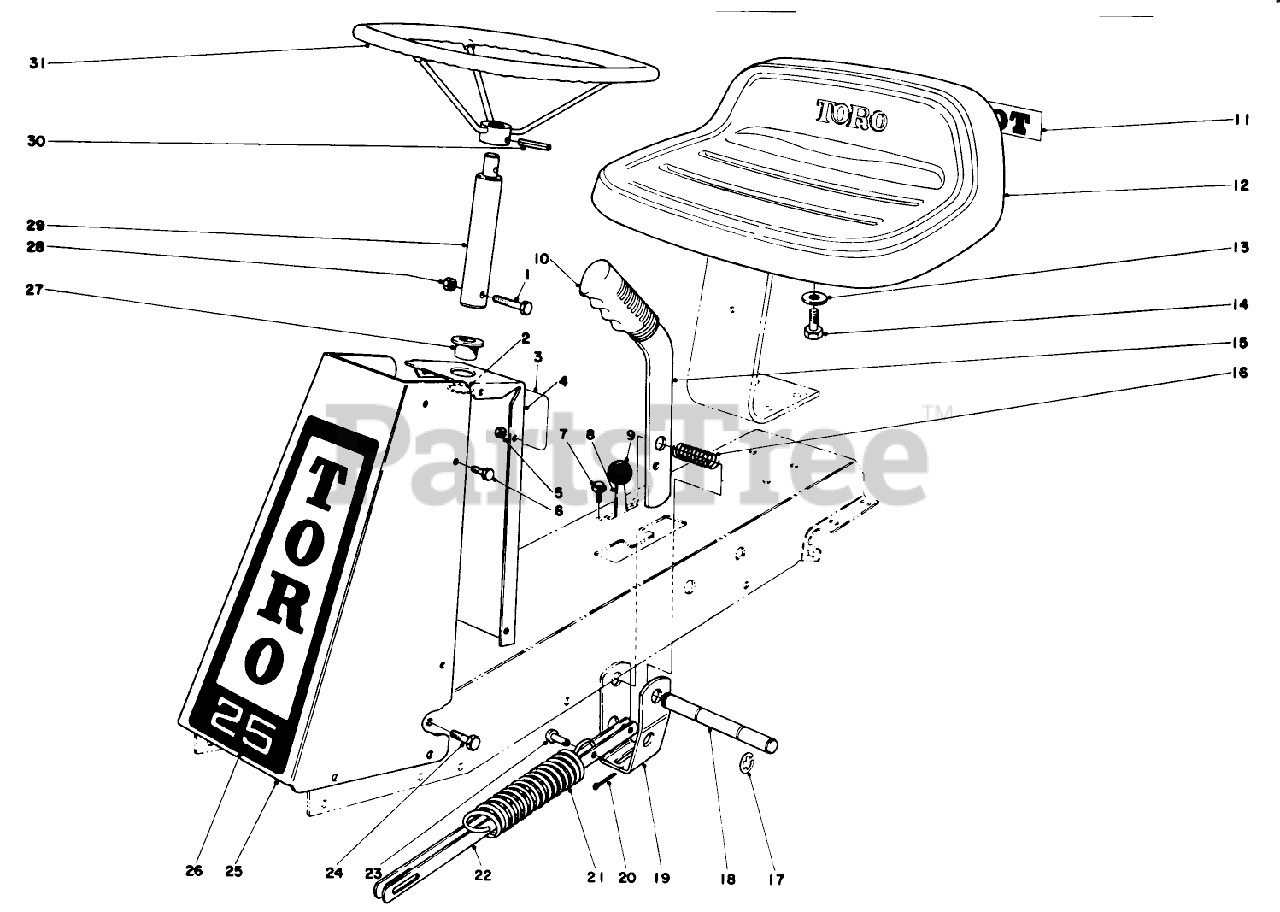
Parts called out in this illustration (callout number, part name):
1	SCREW-HH
2	Retaining Ring
3	Decal-Caution
4	Panel Assembly (Inc. Ref. No. 2 27)
5	NUT-LOCK, CONE
6	SCREW-HH
7	SCREW-HWHTF
8	Throttle Control
9	KNOB-CONTROL
10	Grip Handle
11	Decal
13	WASHER-FLAT
14	HEX HD CAPSCREW
15	Blade Clutch Handle
16	Spring
17	E-RING
18	Blade Handle Shaft
19	Clutch Handle Pivot
20	PIN-COTTER
22	Tie Bar Blade Clutch
23	PIN-CLEVIS
24	SCREW-HH
25	Cover, Steering Column
26	Decal-Toro 25
28	NUT-LOCK, CONE
29	Shaft Steering
30	PIN-ROLL
31	Steering Wheel
